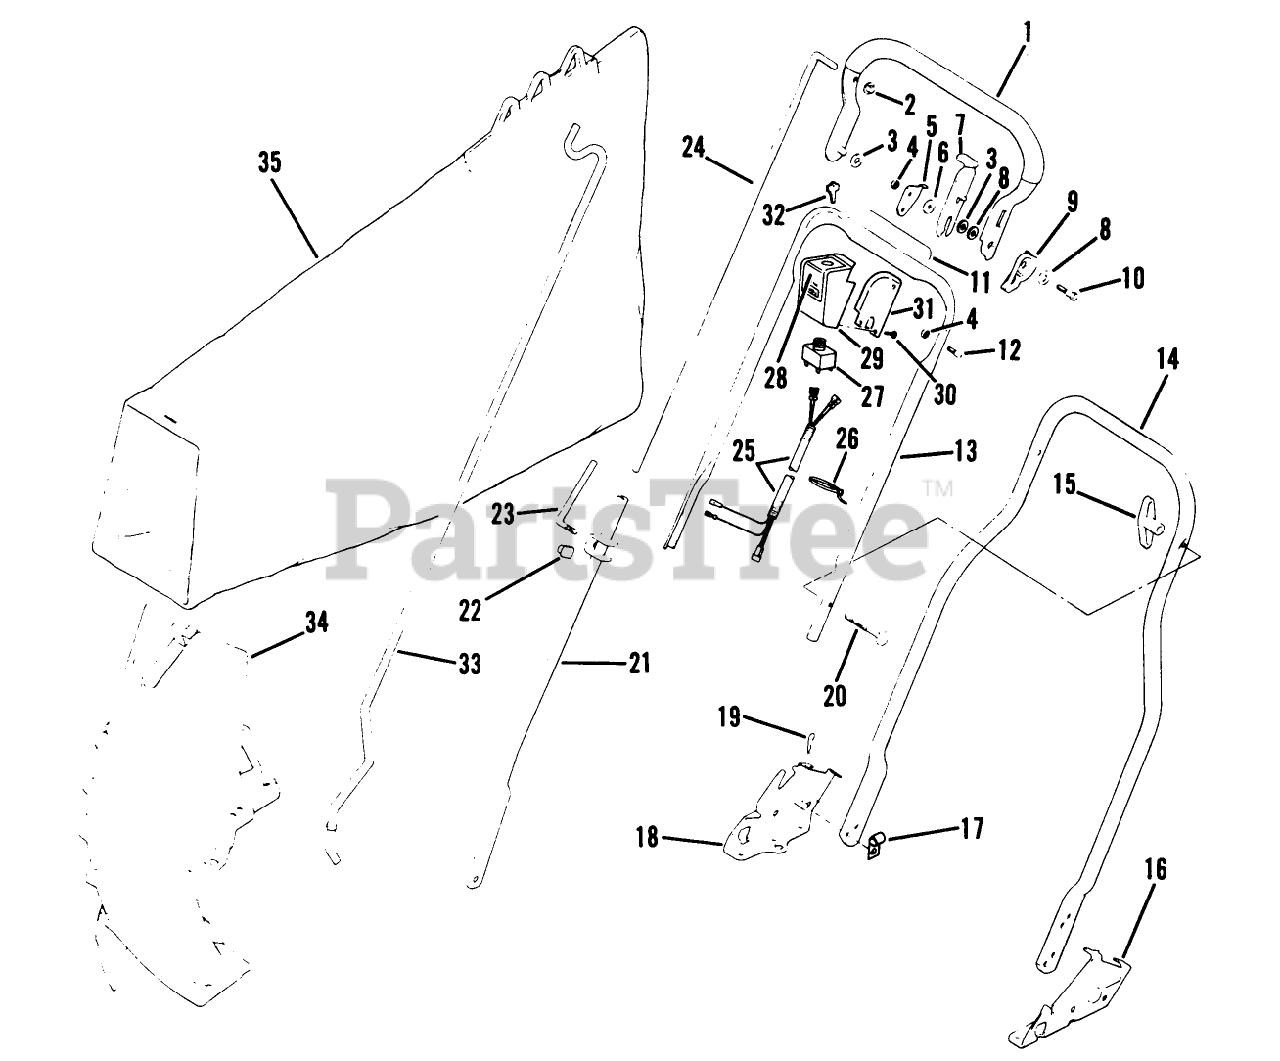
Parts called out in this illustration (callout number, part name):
3	WASHER M
4	LOCKNUT E
5	HANDLE STOP
6	WASHER
7	LEVER LOCKOUT
10	BOLT PIONEER
12	SCREW-HANDLE STOP
13	HANDLE
15	NUT-WING
18	HANDLE BRACKET
19	HAIR PIN
24	ROD CONTROL
29	HOUSING SWITCH
33	ROD GRASSBAG
35	89802 LB WHOLE GOODS
